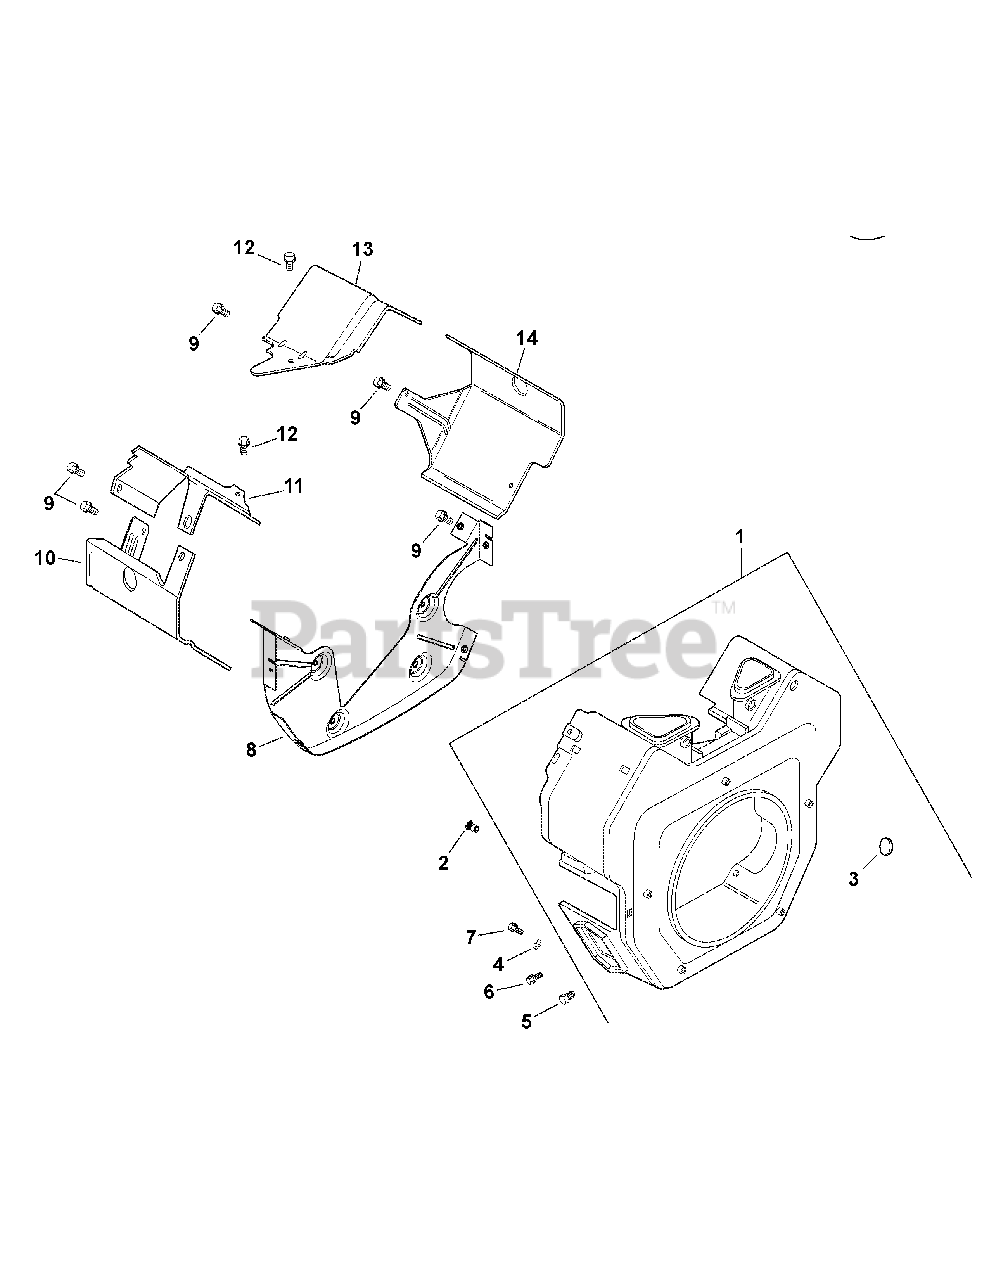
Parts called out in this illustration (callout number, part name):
1	Housing, blower
2	Insert, threaded
4	Washer, flat, 7/32"
5	Screw, hex. Flange M5x0.8x16
6	Screw, hex. Flange M5x0.8x16
7	Screw, hex. Flange M5x0.8x20
8	Plate, back
9	Scr, hex flng M6x1.0x16
10	Bae, cyl barrel #2 side
11	Bae, valley - #2 side
12	Screw, hex flange M5x0.8x10
13	Baffle, valley - #1 side
14	Baffle, cylinder barrel - #1 side
